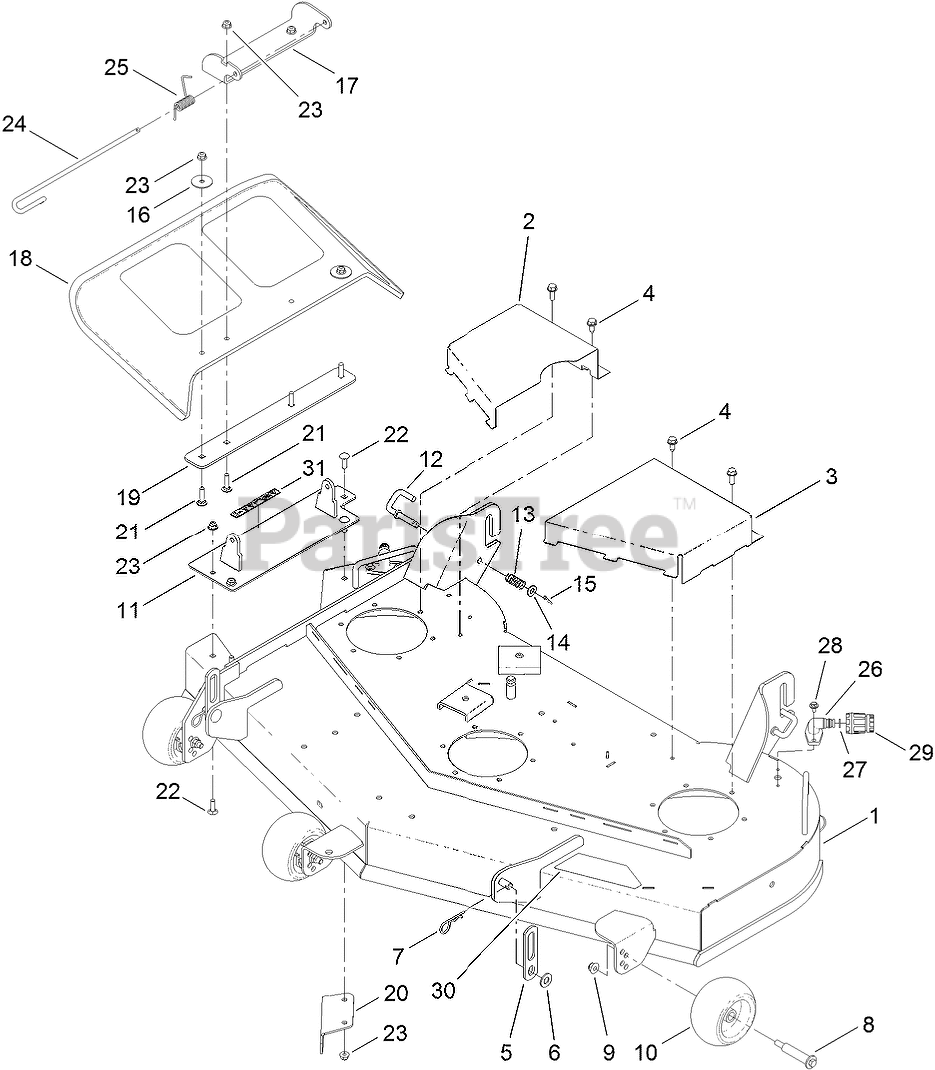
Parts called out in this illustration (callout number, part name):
1	48 INCH DECK AND DECAL ASM
2	COVER-BELT, RH
3	COVER-BELT, LH
4	SCREW-HWHTF
5	LINK-LIFT
6	WASHER-FLAT
7	PIN-COTTER
8	BOLT-SHOULDER
9	NUT-HF, NI
10	ROLLER-SCALP, ANTI
12	PIN-LATCH
13	SPRING-COMPRESSION
14	WASHER-FLAT
15	PIN-COTTER
16	WASHER-FLAT
17	BRACKET-DEFLECTOR, UPPER
18	DEFLECTOR
19	PLATE-DEFLECTOR
20	BAFFLE-CUTOFF
21	SCREW-CARR
22	SCREW-CARR
23	NUT-HF, NI
24	PIN-CHUTE
25	SPRING-TORSION
26	FITTING-WASHOUT
27	O-RING
28	SCREW-HHFTF
29	CONNECTOR-HOSE
30	DECAL-DECK
31	DECAL-DANGER
